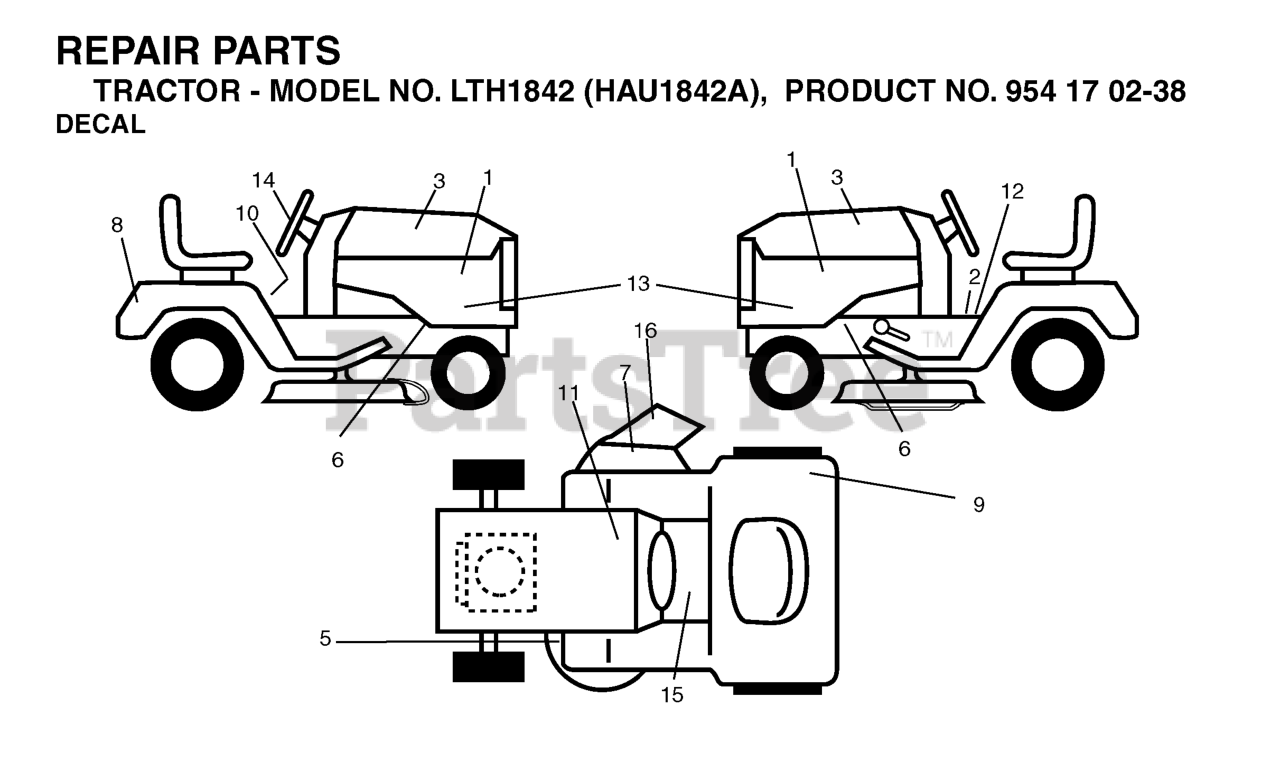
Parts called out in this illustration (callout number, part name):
2	DECAL PARK BRAKE
3	DECAL.HOOD.HUSQVARNA.INTERNATI
5	DECAL V BELT SCHEMATIC
7	DECAL.INTERNATIONL.CUTFINGER
9	DECAL
10	DECAL READ OWNER'S MAN SYMS
11	DECAL BTRY SYMBOLS
12	DECAL
14	DECAL.STEERING.HUSQ.BLUE
15	DECAL
16	DECAL DECK "B" 42"
